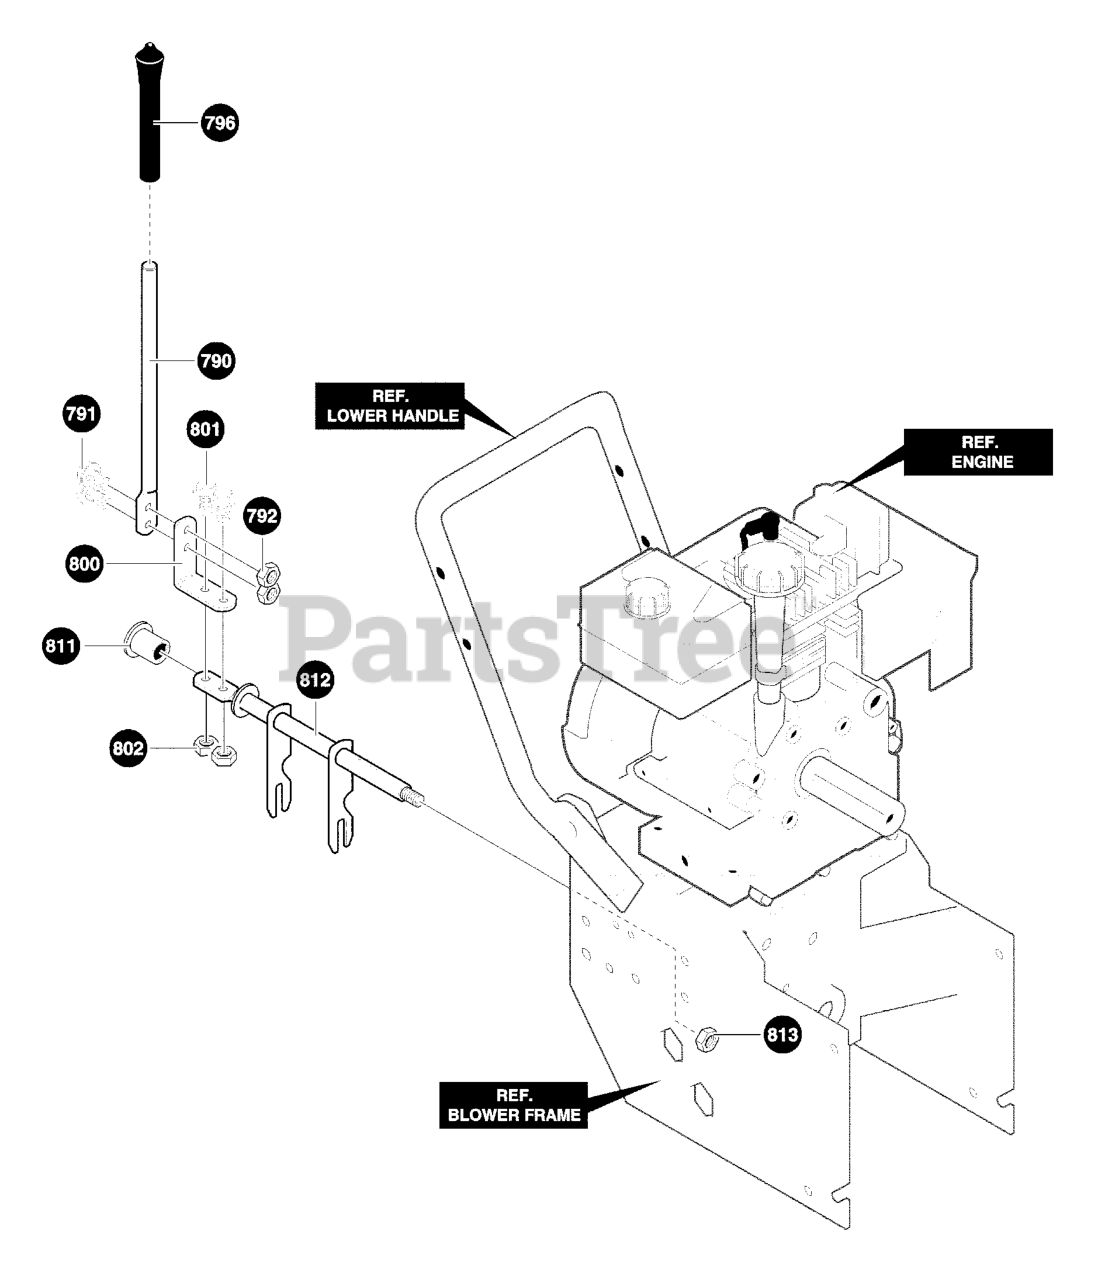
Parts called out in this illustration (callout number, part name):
790	ROD, SHIFT
791	SCREW, 1/4-20X.75
792	NUT, 1/4-20 REGHEXCTRLK
796	KNOB, SLIP
800	LEVER, SPRING
801	SCREW, 1/4-20X.75
802	NUT, 1/4-20 REGHEXCTRLK
811	BEARING, FLANGED
812	ROD, ASSY. YOKE
813	NUT, 3/8-16 HEXCTRLK
